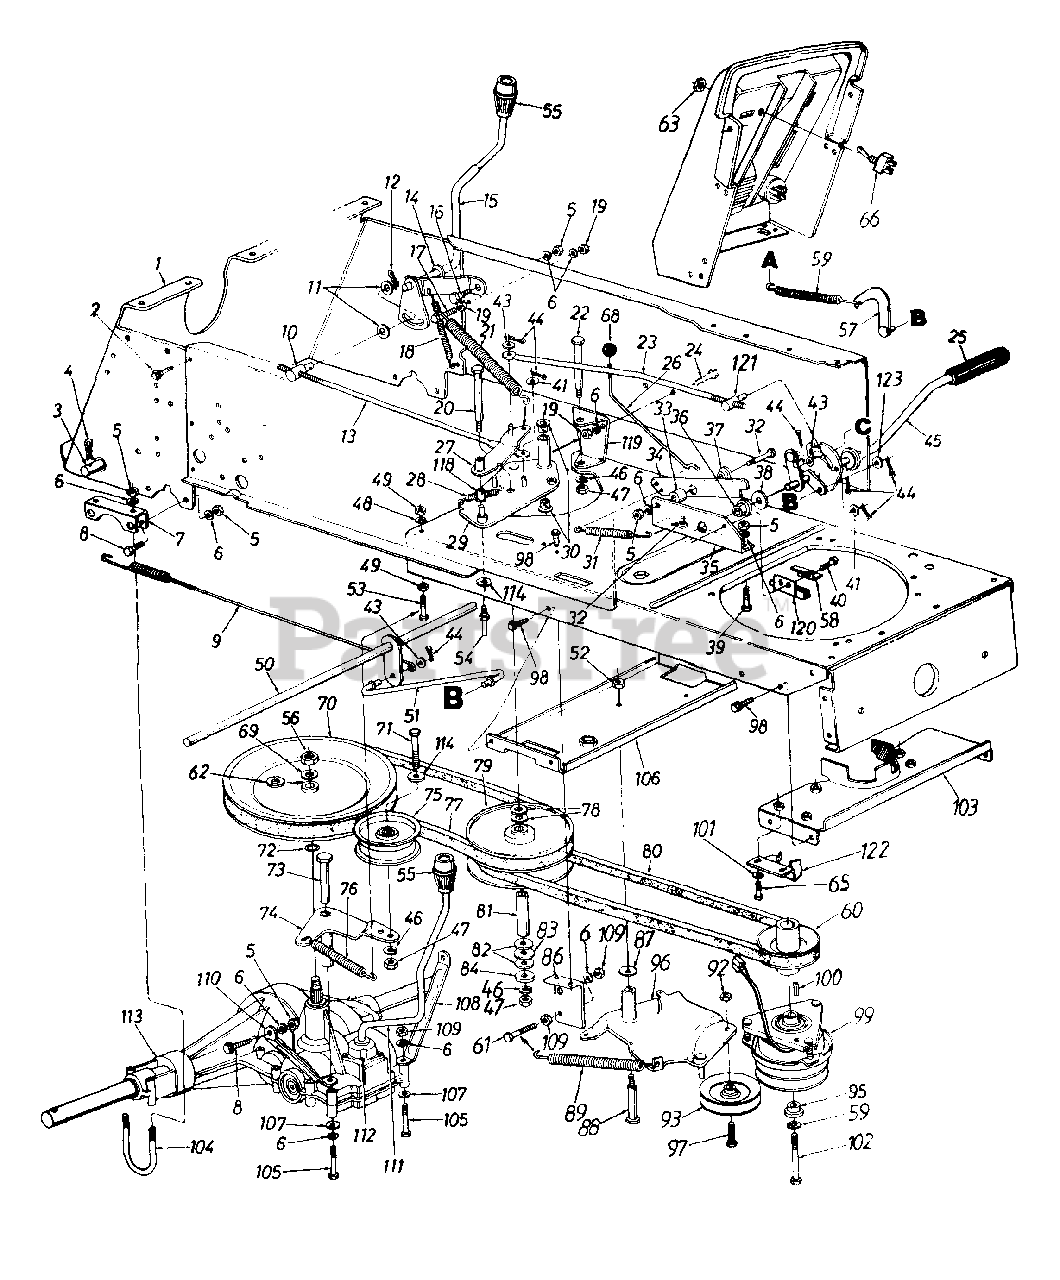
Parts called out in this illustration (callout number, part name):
4	Hitch Pin Clip
5	Hex Nut 5/16-18 Thd.
6	L-Wash. 5/16" I.D."
7	Transaxle Bracket
8	Hex Bolt 5/16-18 x .75" Lg. (Gr. 5)
9	Brake Extension Spring
10	Adjustment Ferrule 3/8-24 Thd.
11	Fl-Wash. .385" I.D. x .87"
13	Speed Control Link (Rear)
14	Fl-Wash. .531" I.D. x .94"
15	Speed Selector Lever Ass'y.
16	Shld. Bolt .437" Dia. x .162"
17	Hex Bolt 5/16-24 x 1.25" Lg.
18	Extension Spring 3.9" Lg.
19	Hex Nut 5/16-24 Thd. (Gr. 5)
20	Hex Bolt 3/8-24 x 4.5" Lg.
21	Extension Spring 11" Lg.
22	Shld. Bolt .625" Dia. x 3.5" Lg.
23	Speed Control Link (Front)
24	Hex Bolt 5/16-24 x .75" Lg.
25	Foot Pad
26	Parking Brake Link
29	Pulley Plate Ass'y.
30	Flanged Brg. .63" I.D.
31	Extension Spring 2.51" Lg.
32	Hex Bolt 5/16-18 x 1.25" Lg.
33	Spacer .34" I.D. x .88"
36	Hex Flange Brg. .634" I.D.
37	Shld. Spacer .5" Dia.
38	Fl-Wash. .64" I.D. x 1.24"
39	Hex Bolt 5/16-18 x .75" Lg.
40	Hex B-Tap Scr. #10 x 5/8" Lg.
41	Fl-Wash. .406" I.D. x .75" O.D.
43	Fl-Wash. .34" I.D. x .68" O.D.
44	Cotter Pin 3/32" Dia.
47	Hex Nut 3/8-24 Thd.
48	L-Wash. 1/4" I.D.
49	Hex Nut 1/4-20 Thd.
50	Brake Link Bracket
51	Front Brake Rod Link
52	Hex Cent. L-Nut 3/8-16 Thd.
53	Hex Bolt 1/4-20 x 2.0" Lg.
54	Belt Guard Pin
56	Hex Jam Nut 9/16-18 Thd.
57	Foot Pedal Brkt. Ass'y.
58	Switch Plate
59	Ext. Spring 5.2" Lg.
60	Engine Pulley
61	Hex Bolt 5/16-24 x 1.75" Lg.
62	Fl-Wash. .635" I.D. x 1.12" O.D.
63	Hex Nut 1/2-27 Thd.
65	Hex Bolt 5/16-18 x .75" Lg (Gr. 5)
66	Toggle Switch
68	Ball Knob Brake
69	Bell-Wash. 9/16" I.D. x 1.25"
70	V-Pulley 9-1/4" O.D.
71	Hex Bolt 3/8-24 x 1.75" Lg.
73	Shld. Bolt 5/16-24 Thd.
74	Idler Brkt. Ass'y.
75	Flat Idler 3.5" O.D.
76	Extension Spring 6.12" Lg.
77	V-Belt
78	Teflon Washer 1.20" O.D.
79	Variable Speed Pulley 6" Dia.
80	V-Belt
81	Pivot Bushing
82	Fl-Wash. .56" I.D. x 1.0" O.D.
83	Thrust Brg. .56" I.D. x 1.25"
84	Retainer Cup
86	Parking Brake Mtg. Brkt.
87	Bell-Wash. .38" I.D. x .88" O.D.
88	Shld. Bolt .498" Dia. x 2.05"
89	Extension Spring 4.0" Lg.
92	Hex Cent. L-Nut 3/8-24 Thd.
93	V-Belt Idler
95	Shoulder Spacer
96	Idler Brkt. Deck Ass'y.
97	Hex Bolt 3/8-24 x 1.5" Lg.
98	Hex TT-Tap Scr. 1/4-20 x .5"
99	Electric Clutch
100	Sq. Key 1/4 x 1.5" Lg.
101	Bell-Wash. .345" I.D. x .88"
102	Hex Bolt 7/16-20 x 3.75" Lg.
103	Belt Keeper Brkt. Ass'y.
105	Hex Bolt 5/16-24 x 2.25" Lg.
106	Deck Idler Support Brkt.
107	Fl-Wash. .344" I.D. x .62" O.D.
108	Front Trans. Support Brkt. - L.H,
109	Hex Nut 5/16-24 Thd.
110	Front Trans. Support Brkt. - R.H.
111	Shift Lever Ass'y. Complete
112	Socket Hd. Cap Scr. #10 x 24
113	2-Speed Transmission Comp.
114	Fl-Wash. 3/8" I.D. x 1.0" O.D.
118	Nyliner Flanged Brg.
119	Variable Speed Support Brkt.
120	Safety Switch (Clutch)
121	Adjustment Ferrule 3/8-24 Thd.
